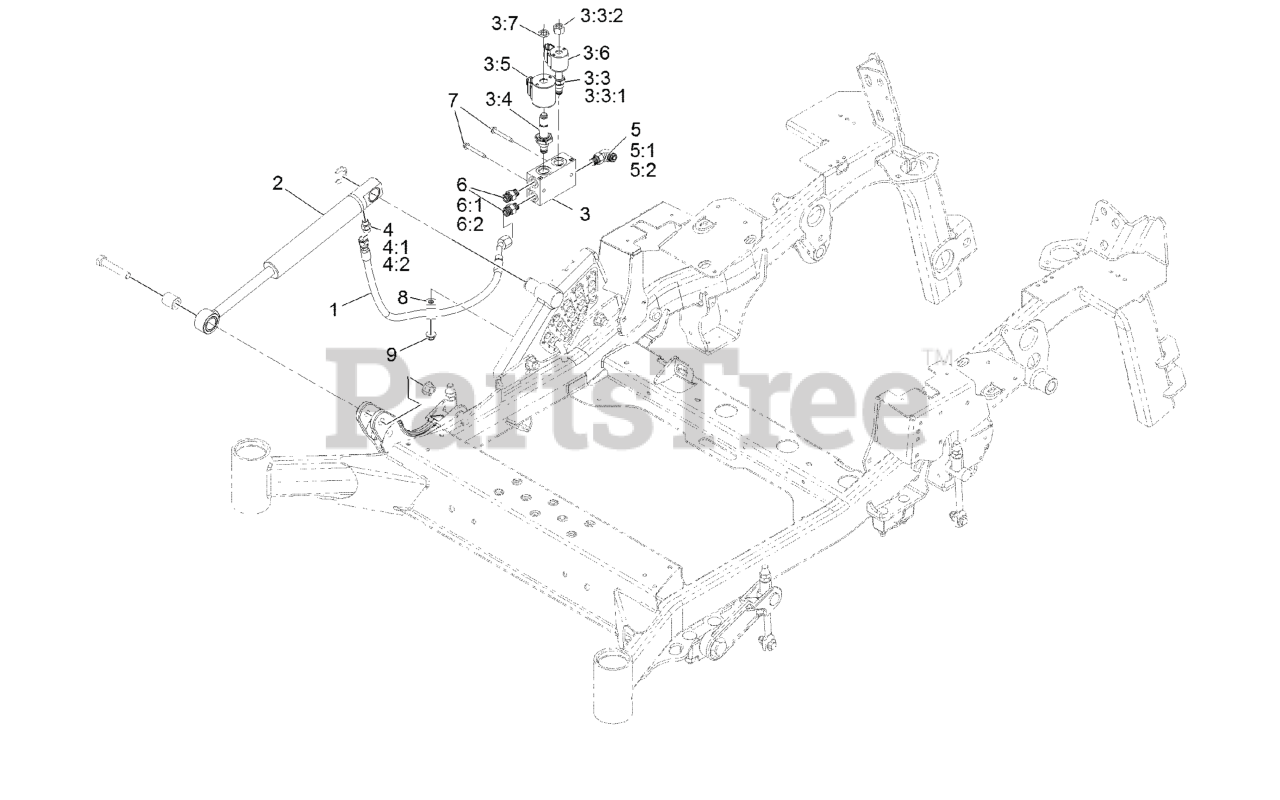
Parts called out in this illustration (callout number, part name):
1	HOSE ASM
2	CYLINDER-LIFT
3	DECK LIFT VALVE ASM
3:3	VALVE-SOLENOID
3:3:1	SEAL KIT
3:3:2	NUT-SOLENOID
3:4	VALVE-SOLENOID
3:5	COIL-12V
3:7	NUT-COIL
4	FITTING-HYD, STRAIGHT
4:1	O-RING
4:2	O-RING
5	FITTING-ELBOW, 90 DEG
5:1	O-RING
5:2	O-RING
6	FITTING-STRAIGHT
6:1	O-RING
6:2	O-RING
7	SCREW-HWHTF
8	CLIP-LOOM
9	NUT-HF, NI
